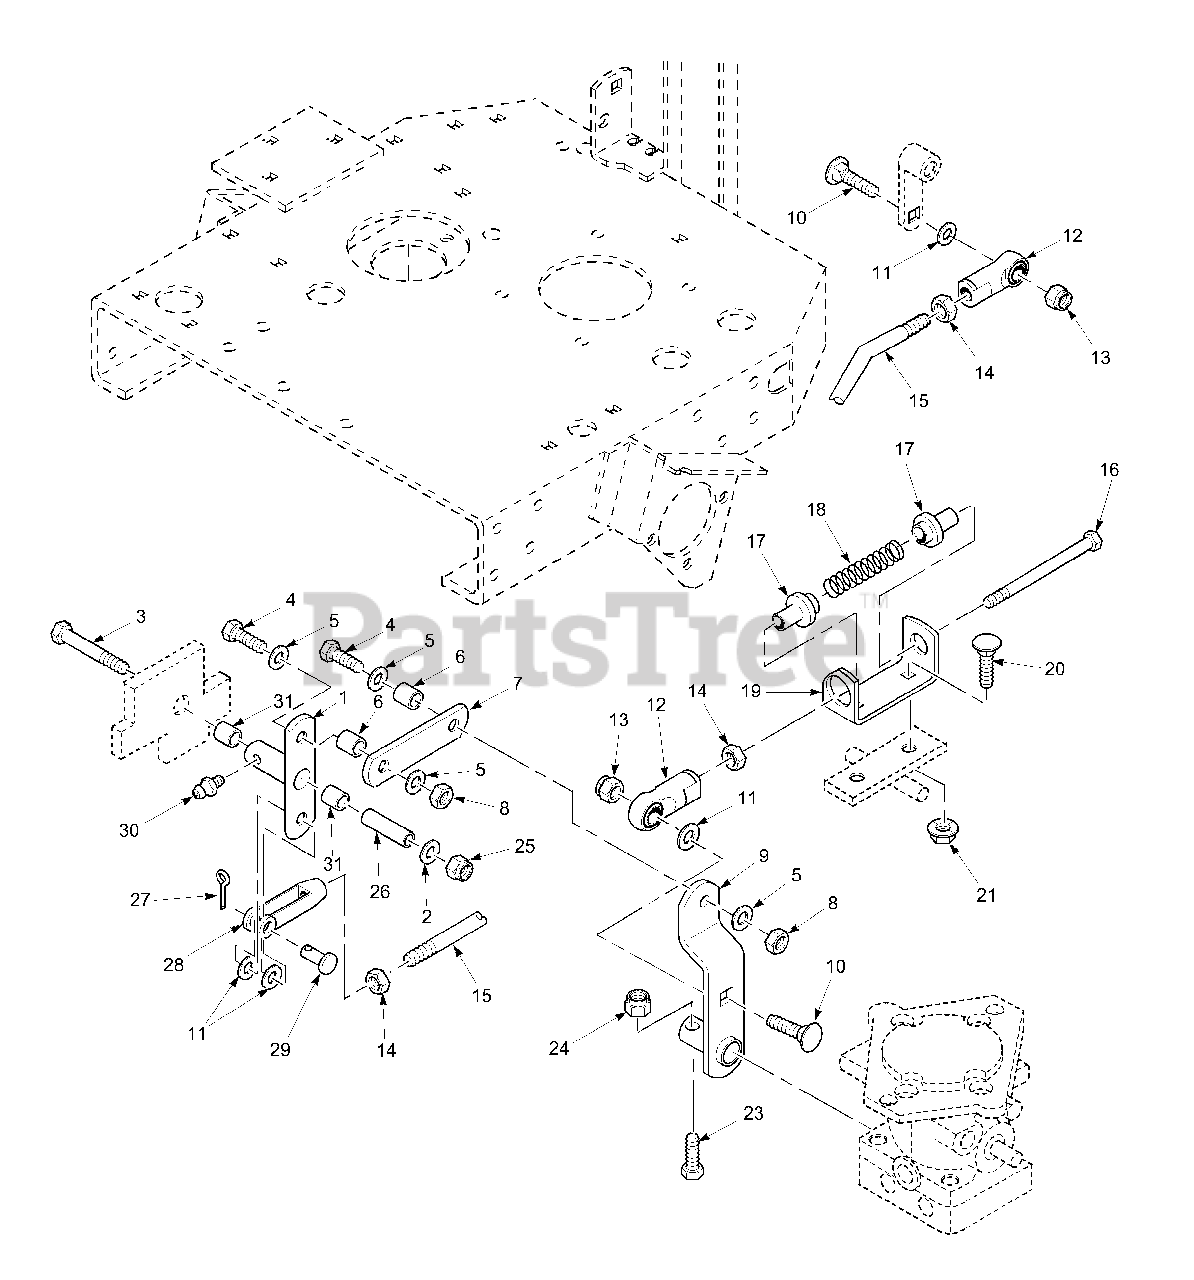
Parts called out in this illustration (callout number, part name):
1	Control Linkage, Bellcrank
2	Flatwasher, 5/16 (.375 x .875 x .083)
3	Bolt, Hex Head 5/16-18 x 2-3/4"
4	Bolt, Hex Head 3/8-16 x 1"
5	Flatwasher, 3/8 (.406 x .812 x .065)
6	Sleeve, Pump Control Link
7	Link, Speed Control
8	Hex Locknut, 3/8-16
9	Control Arm, Pump
10	Carrage Bolt,RH SH SQNK 3/8-16 x 1-1/2"
11	Flatwasher, 3/8 (.391 x .938 x .105)
12	Rod End, RH Female THD 3/8-24
13	Hex Locknut, Elastic Stop 3/8-16
14	Hex Nut, 3/8-24
15	Control Rod
16	Bolt Hex Head, 3/8-24 x 6-3/4"
17	Bushing, Spring Keeper
18	Spring, Neutral Return
19	Retainer, Neutral Spring
20	Carrage Bolt, 5/16-18 x 1"
21	Serr. Fl. Hex Nut 5/16-18
23	Bolt, Hex Head 1/4-20 x 1-1/4"
24	Hex Locknut, Elastic Stop 1/4-20
25	Hex Locknut, Elastic Stop 5/16-18
26	Sleeve, Control Arm
27	Cotter Pin, 3/32 x .75"
28	Clevis, Pump Control
29	Pin, Clevis 3/8"
30	Greese Fitting, 1/4-28 Self Tap
31	Bushing, Bronze
